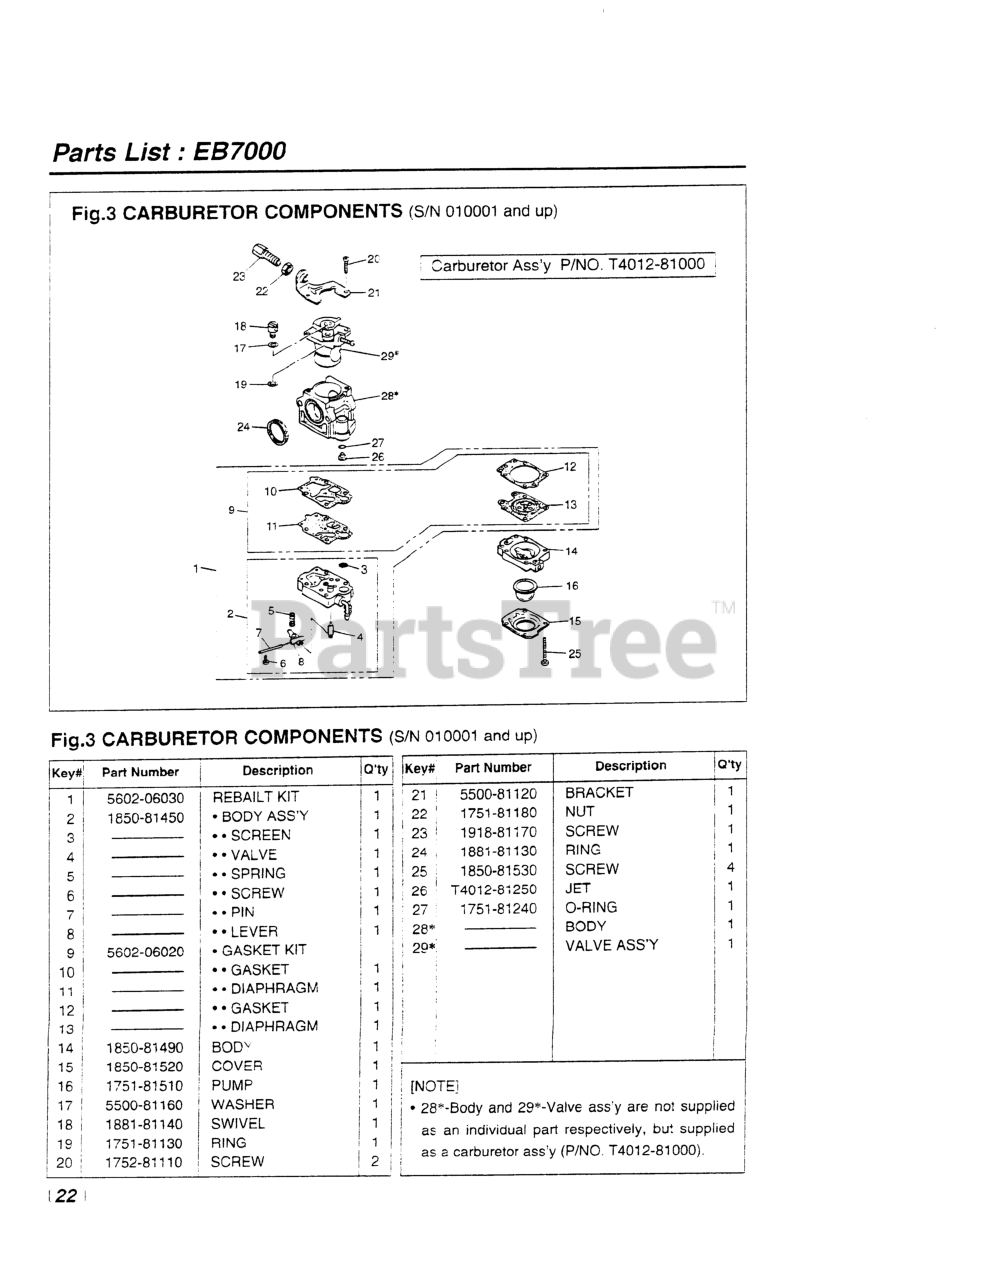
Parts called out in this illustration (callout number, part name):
2	BODY, PUMP
3	SCREEN
4	VALVE, INLET
6	SCREW
7	PIN
8	LEVER
10	GASKET
11	DIAPHRAGM
12	GASKET
13	DIAPHRAGM
14	BODY, PURGE
15	COVER, PUMP
16	PUMP, PRIMING
17	WASHER
18	SWIVEL
19	RING
20	SCREW
22	NUT, CABLE ADJUSTER
23	SCREW, CABLE ADJUSTER
24	RING, PACKING
25	SCREW
26	JET
27	RING, O
28	CARBURETOR (WYK-123-1)
29	CARBURETOR (WYK-123-1)
